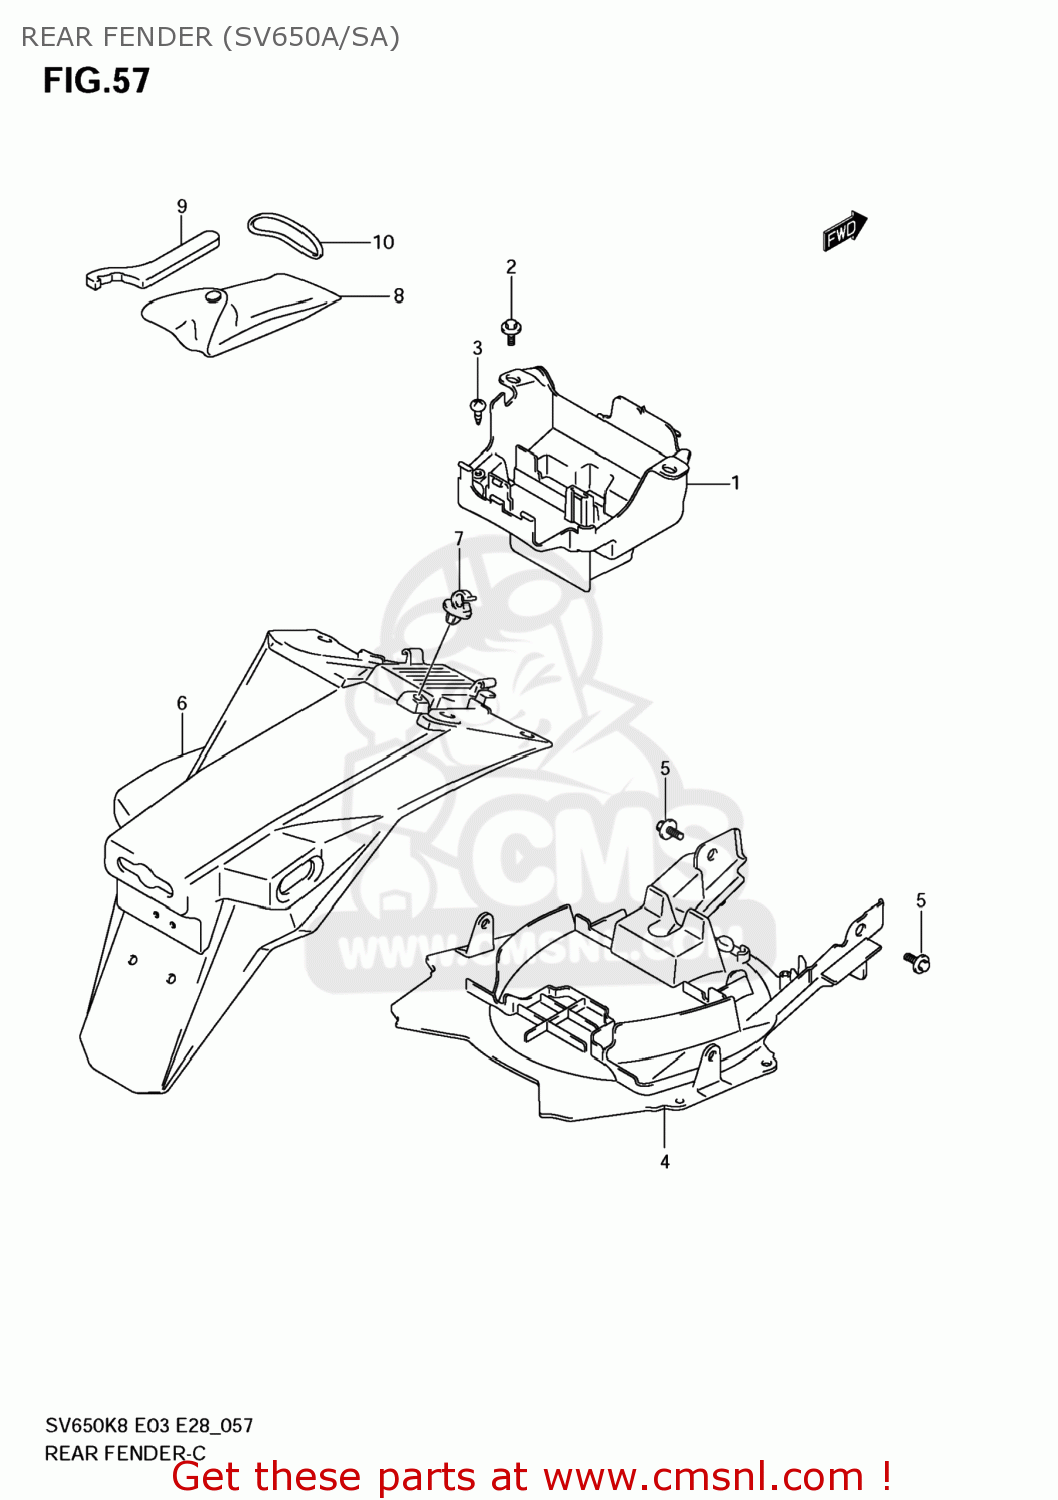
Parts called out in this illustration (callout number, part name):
1	HOLDER,BATTERY
2	BOLT
3	SCREW
4	FENDER,RR FR
5	BOLT(6X12)
6	FENDER,RR RR
7	CLAMP
8	TOOL ASSY
9	CLAMP
10	O RING(D:3.5,ID:61)
